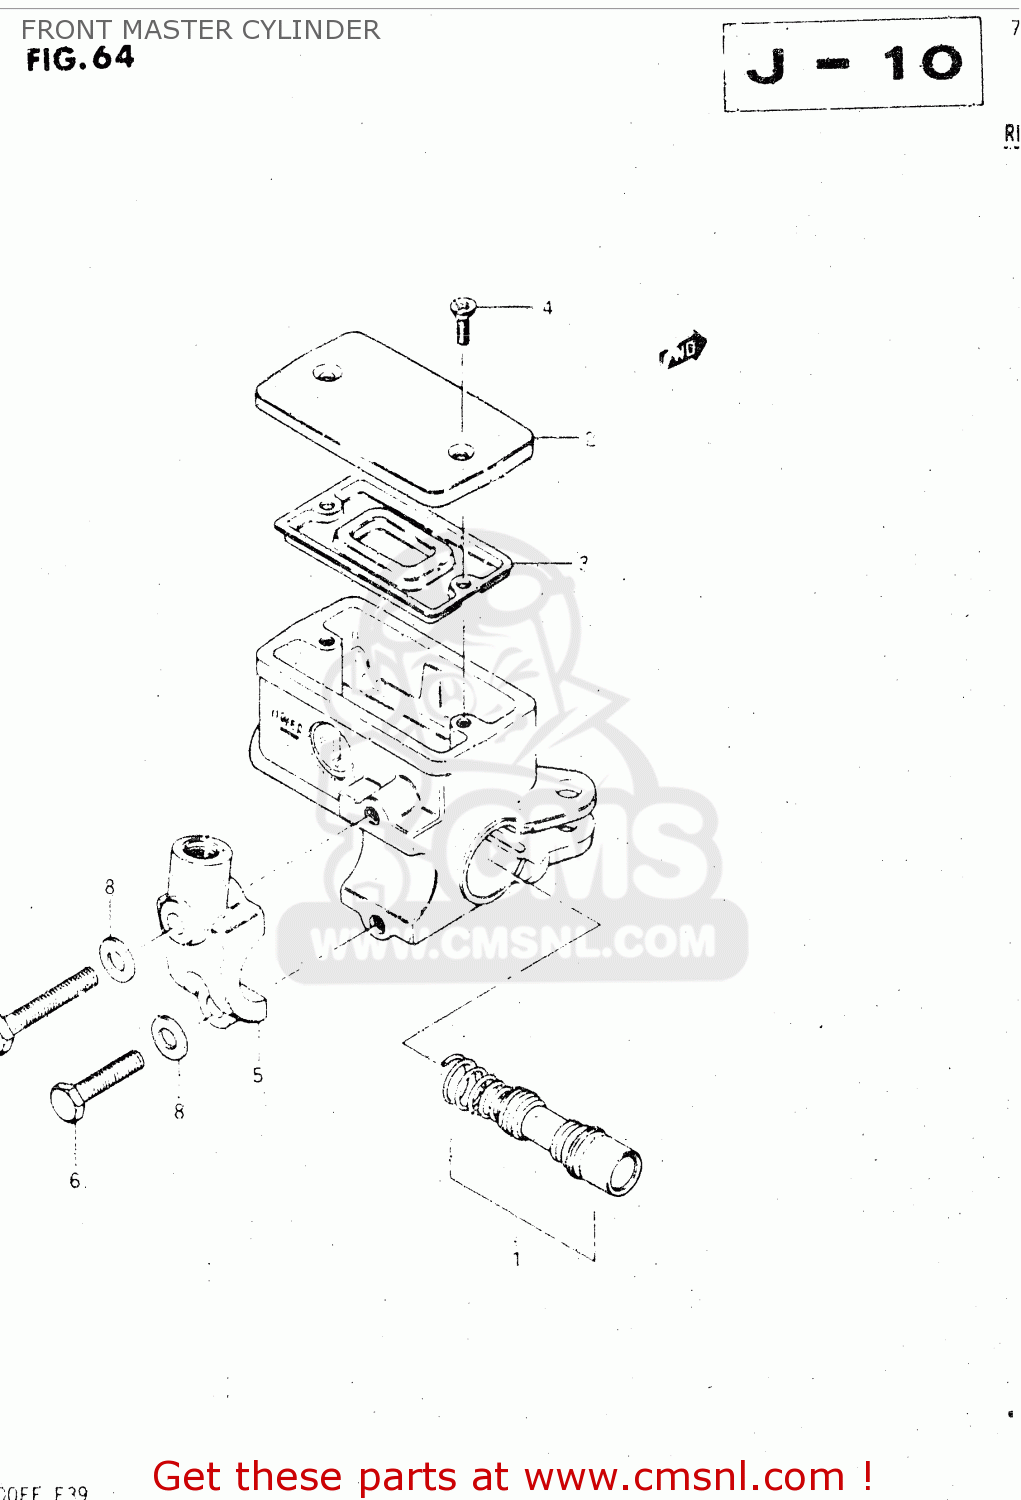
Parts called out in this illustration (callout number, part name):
1	PISTON & CUP SET
2	CAP
3	4
4	SCREW
5	HOLDER
6	BOLT
7	BOLT
8	WASHER
